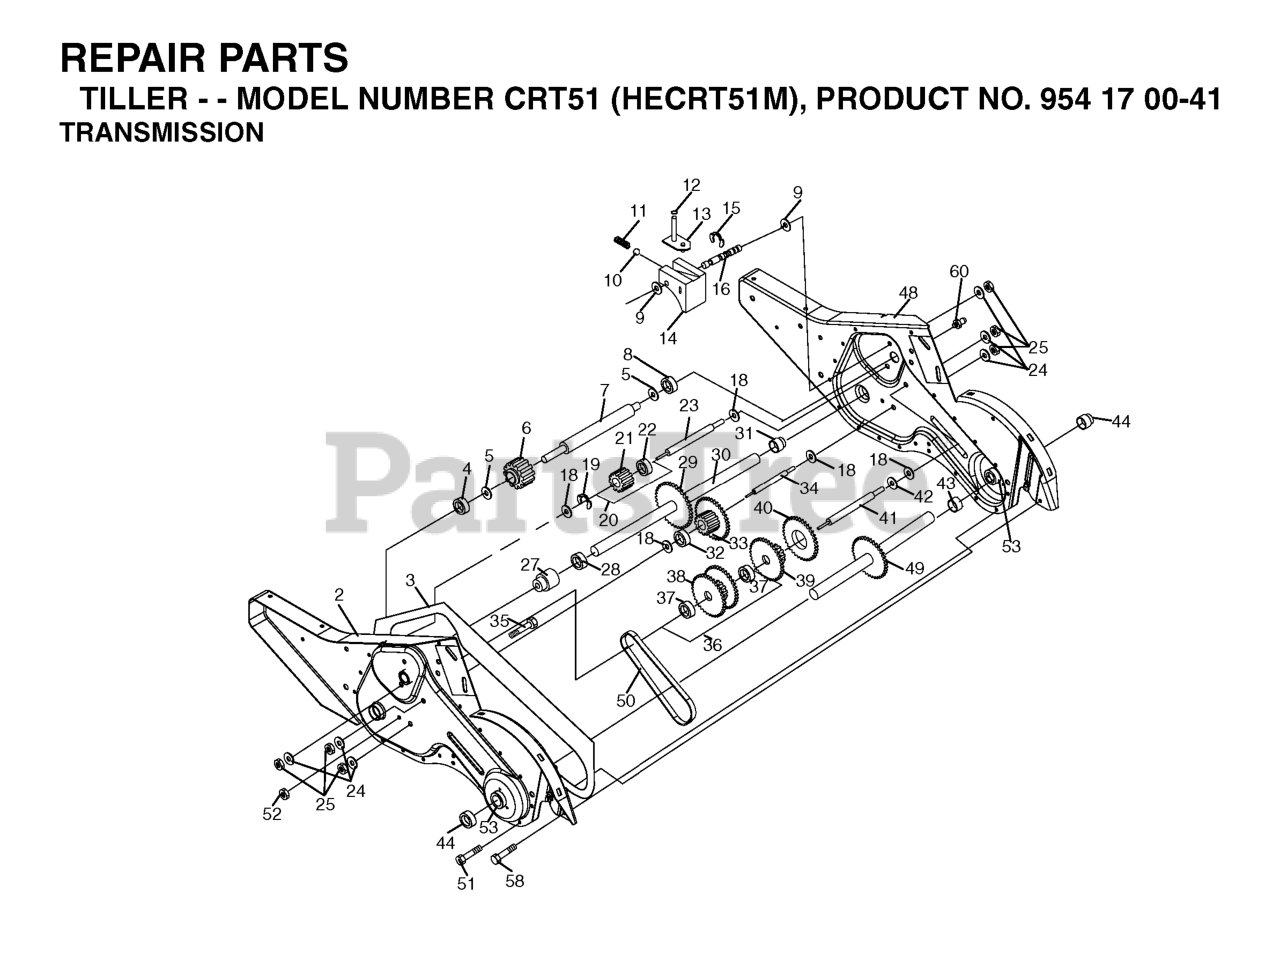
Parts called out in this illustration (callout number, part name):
1	TRANS SERV
2	GEAR CASE
3	GASKET
4	NEEDLE BRNG LT
5	THRUST WASHER
6	GEAR.PINION.INPUT
7	SHAFT.INPUT."D".TILLER
8	BEARING TI
9	WASHER, SEAL (2 2)
10	STEEL BALL KIT
11	SPRING-SHIFT CRT
13	BRACKET ASM.SHIFT.CRT
14	SHIFT FORK TI
16	SHAFT.SHIFTER.TILLER
20	GEAR ASSY CRT
21	GEAR-REV IDLR CRT
22	NEEDLE BEARING TI
24	LOCKWASHER
25	NUT.ASF.HEX.7/16
27	BEARING, SHAFT LH CRT
30	GROUND SHAFT ASS'Y
31	BEARING, SHAFT RH CRT
33	SPRCKT 8 GEAR CRT
34	SHAFT.SECONDARY.REDUCTION.CRT
35	SCRW WHIZ LOK CRT
36	SPROCKET.ASM.W/BEARING.TILLER
37	BEARING
38	SPROCKET, TINE
41	SHAFT.REDUCTION.TILLER
42	BRNG RACE T
44	SEAL ASM, OIL
48	GEARCASE, R.H. W/BEARING
49	TINE SHAFT
50	CHAIN.TILLER
51	SCREW
53	KIT.BEARING.TILLER.
58	BOLT SHOULDER 1/4-20 UNC X.875
60	FITTING.GREASE.TAPERED
